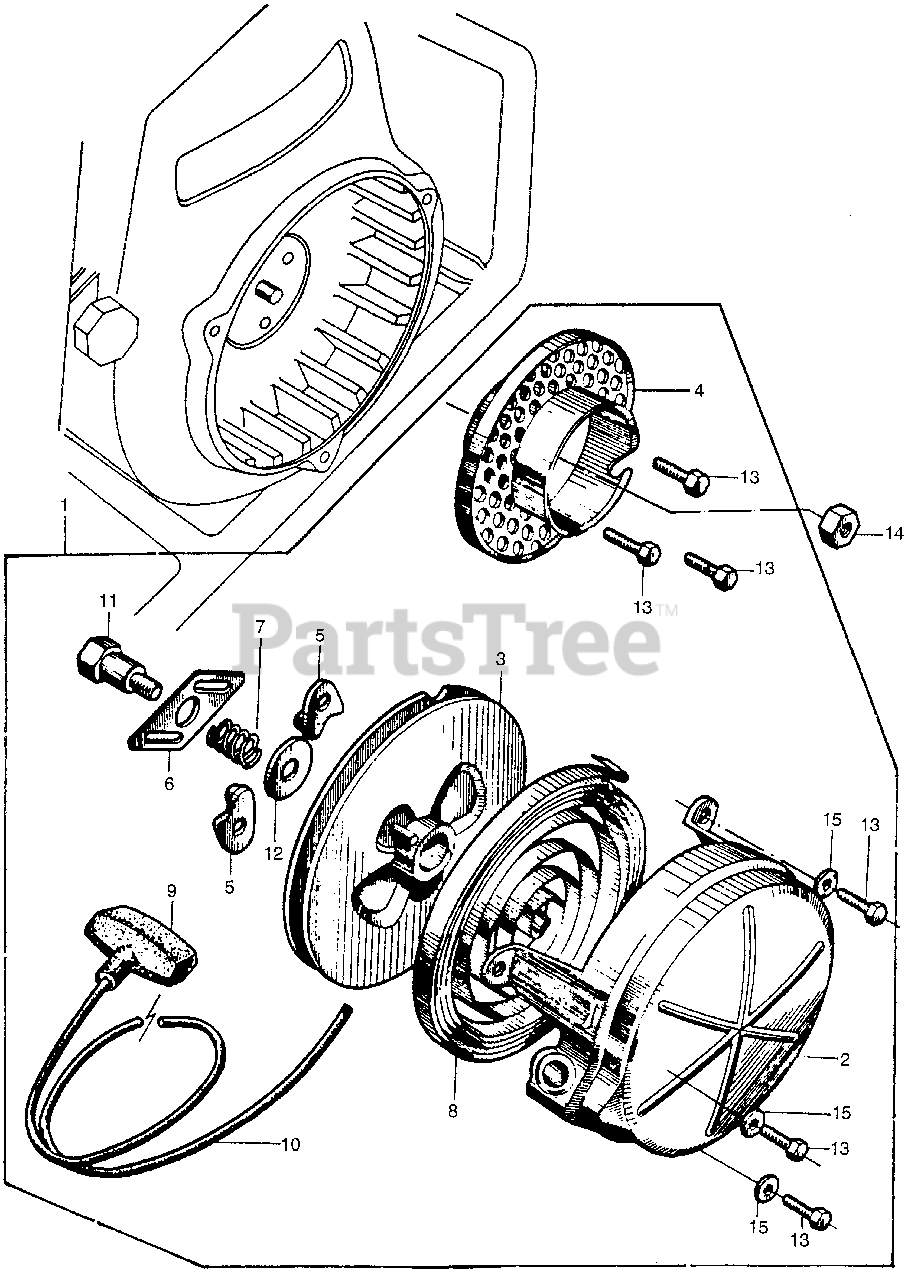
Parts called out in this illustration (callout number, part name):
1	STARTER ASSY., RECOIL *R2* (SCARLET) (NOT AVAILABLE)
2	CASE, RECOIL STARTER (NOT AVAILABLE)
3	PULLEY, RECOIL STARTER
4	PULLEY, STARTER RATCHET (NA USE ALT:28400-806-305C)
5	RATCHET, STARTER
6	PLATE, FRICTION
7	SPRING, FRICTION
8	SPRING, STARTER RETURN (NOT AVAILABLE)
9	KNOB, STARTER
10	ROPE, STARTER (N/A: USE ALT P/N 08560-ZG921-11)
11	BOLT, SPECIAL (8MM)
12	WASHER (8MM) (NOT AVAILABLE)
13	BOLT, HEX. (6X8)
14	NUT, HEX. (8MM)
15	WASHER, PLAIN (6MM)
